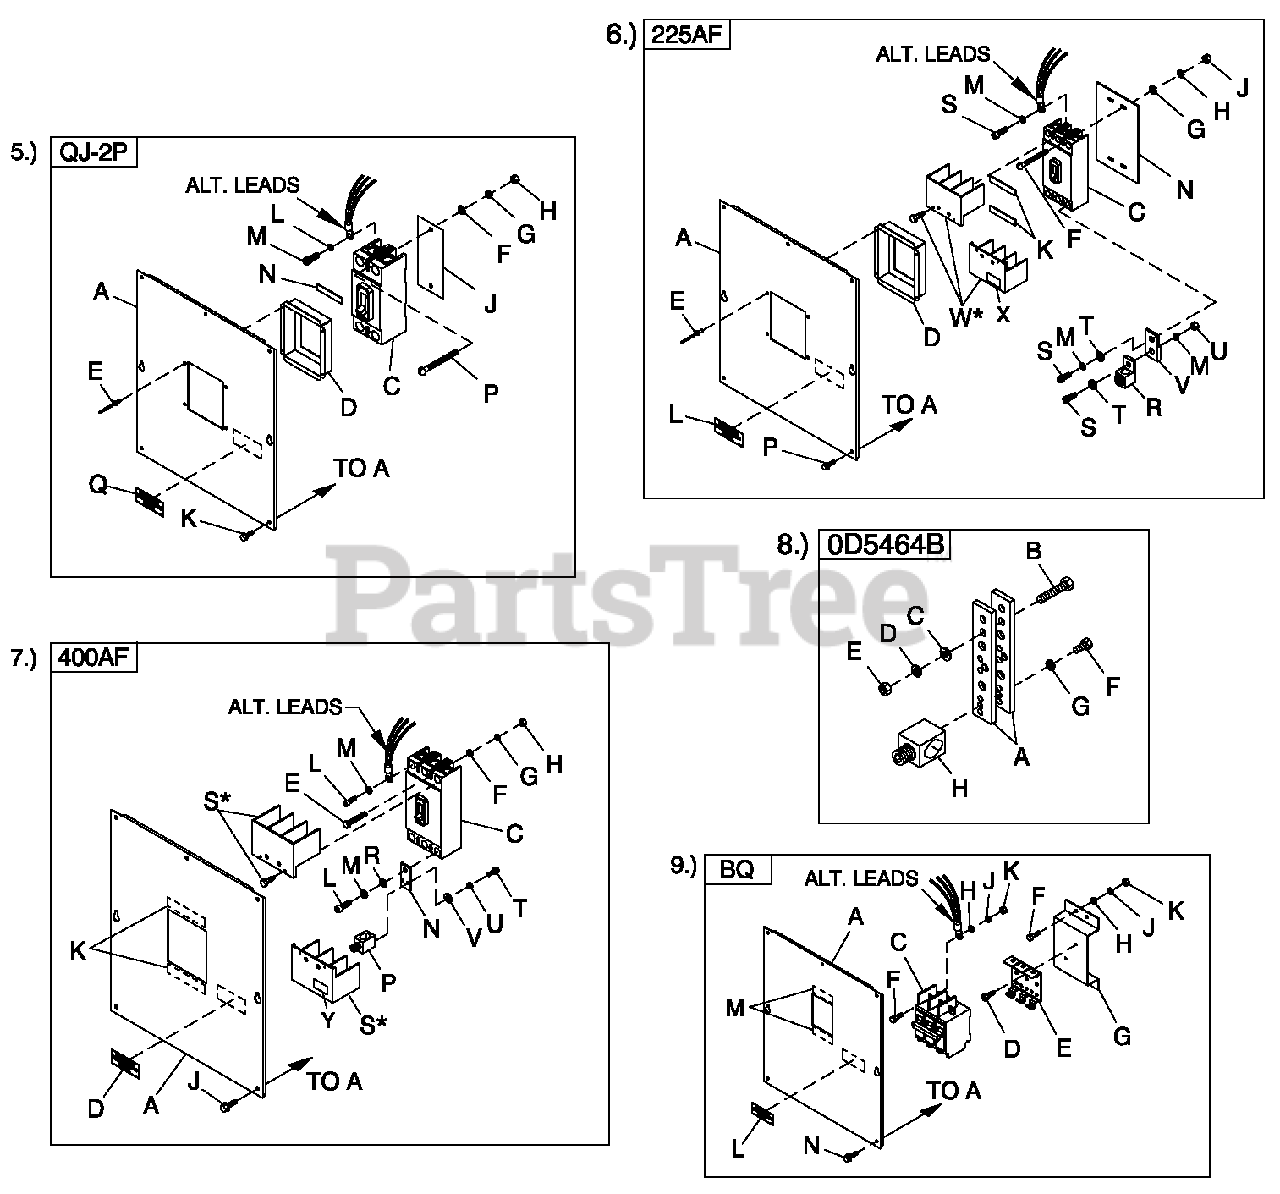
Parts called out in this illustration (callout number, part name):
9	UL CIRCUIT BREAKER (BQ)
A	COVER QJ 2P FRM CB
C	CB 0225A 240V 2P S QJ22
D	COVER QJ 2P CB DISH
E	RIVET POP .125 X .275 SS
F	WASHER FLAT 1/4-M6 ZINC
G	WASHER LOCK M6-1/4
H	NUT HEX 1/4-20 STEEL
J	INSUL CB 2P QJ
K	SCREW THF M6-1 X 16 N WA Z/JS
L	WASHER LOCK 3/8
M	SCREW SHC 3/8-16 X 3/4 G8.8 NZ
N	TAPE ELEC 1/2 FOAM (AS REQ'D)
P	SCREW RHM 1/4-20 X 3
Q	DECAL CUSTOMER CONNECT INSIDE
A	COVER CB C2-C4 225AF
C	CIRCUIT BREAKERS 200A FRAME
D	COVER CB DISH 225AF
F	SCREW RHM #8-32 X 3-1/4
G	WASHER FLAT #8 ZINC
H	WASHER LOCK #8-M4
J	NUT HEX #8-32 STEEL
K	TAPE ELEC 1/2 FOAM
L	DECAL CUSTOMER CONNECT INSIDE
M	WASHER LOCK M8-5/16
N	INSULATOR CB 225AF
P	SCREW THF M6-1 X 16 N WA Z/JS
R	LUG SLDLSS 300 MCM-6 AL/CU
S	SCREW SHC M8-1.25 X 20 G8
T	WASHER FLAT 5/16-M8 ZINC
U	NUT HEX M8-1.25 G8 CLEAR ZINC
V	BUS BAR 200A LUG ADAPTOR
W	TERMINAL COVER CB
X	DECAL TERMINAL SHOCK HZD BI
A	COVER CB C2-C4 400AF
C	CIRCUIT BREAKERS 400A FRAME
D	DECAL CUSTOMER CONNECT INSIDE
E	SCREW RHM 10-32 X 4
F	WASHER FLAT #10 ZINC
G	WASHER LOCK #10
H	NUT HEX #10-32 STEEL
J	SCREW THF M6-1 X 16 N WA Z/JS
L	SCREW SHC M10-1.5 X 25 G12.9
M	WASHER LOCK M10
N	BUS BAR CB ADAPTER 225-400 A
P	LUG SLDLSS 600/250-1/0 X 1/4-28
S	TERM COVER CB
T	SCREW HHC 1/4-28 X 1/2 G5
U	WASHER LOCK M6-1/4
V	WASHER FLAT 1/4-M6 ZINC
Y	DECAL TERMINAL SHOCK HZD BI
A	BUS BAR NEUTRAL BLOCK 390
B	SCREW HHC M8-1.25 X 45 G8.8 FT
C	WASHER FLAT 5/16-M8 ZINC
D	WASHER LOCK M8-5/16
E	NUT HEX M8-1.25 G8 YEL CHR
F	SCREW HHC 1/4-28 X 3/4 G5
G	WASHER LOCK 1/4-M6 SS
H	LUG SLDLSS 600/250-1/0 X 1/4-28
A	COVER BQ CIR BREAKER CPL 3P
C	CB 0125A 2P 240V S BQ2 LL
D	SCREW PHTT M4-0.7 X 10 ZYC
E	BRKT CB MTG BACK
F	SCREW RHM #10-32 X 3/4
G	BRKT BQ CB STANDOFF
H	WASHER FLAT #10 ZINC
J	WASHER LOCK #10
K	NUT HEX #10-32 STEEL
M	TAPE ELEC 1/2 FOAM
N	SCREW THF M6-1 X 16 N WA Z/JS
